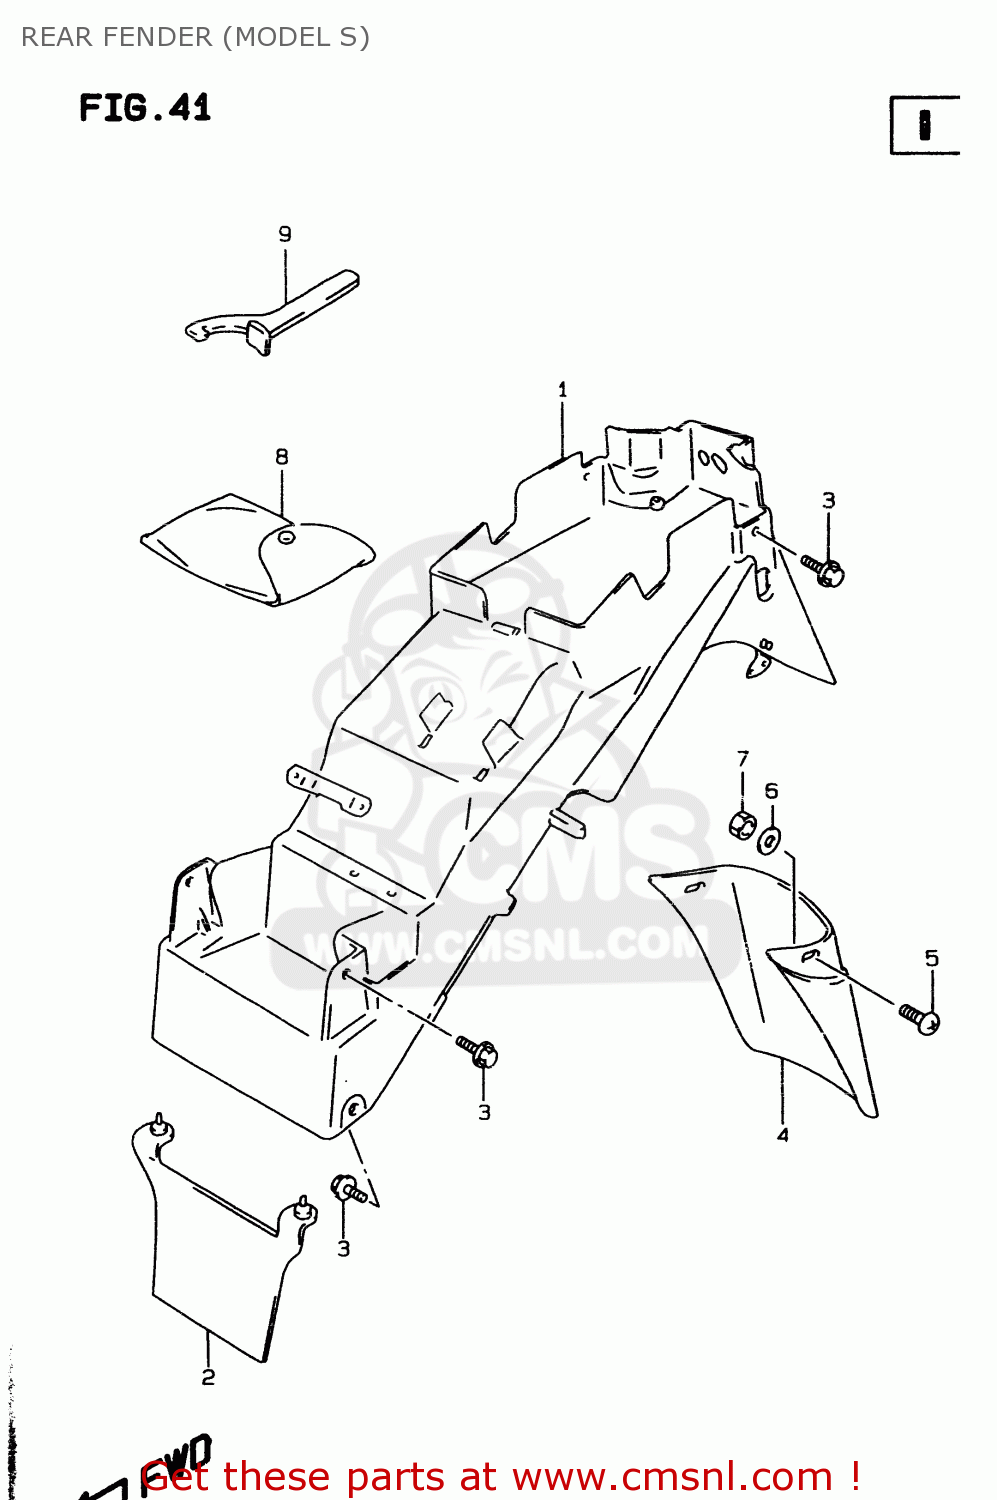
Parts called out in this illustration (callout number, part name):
1	FENDER, REAR
2	MUDGUARD,RR FENDER FR
3	BOLT(6X16)
4	EXTENSION, REAR FENDER
5	SCREW
6	WASHER
7	NUT 6MM
8	TOOL ASSY
9	CLAMP
